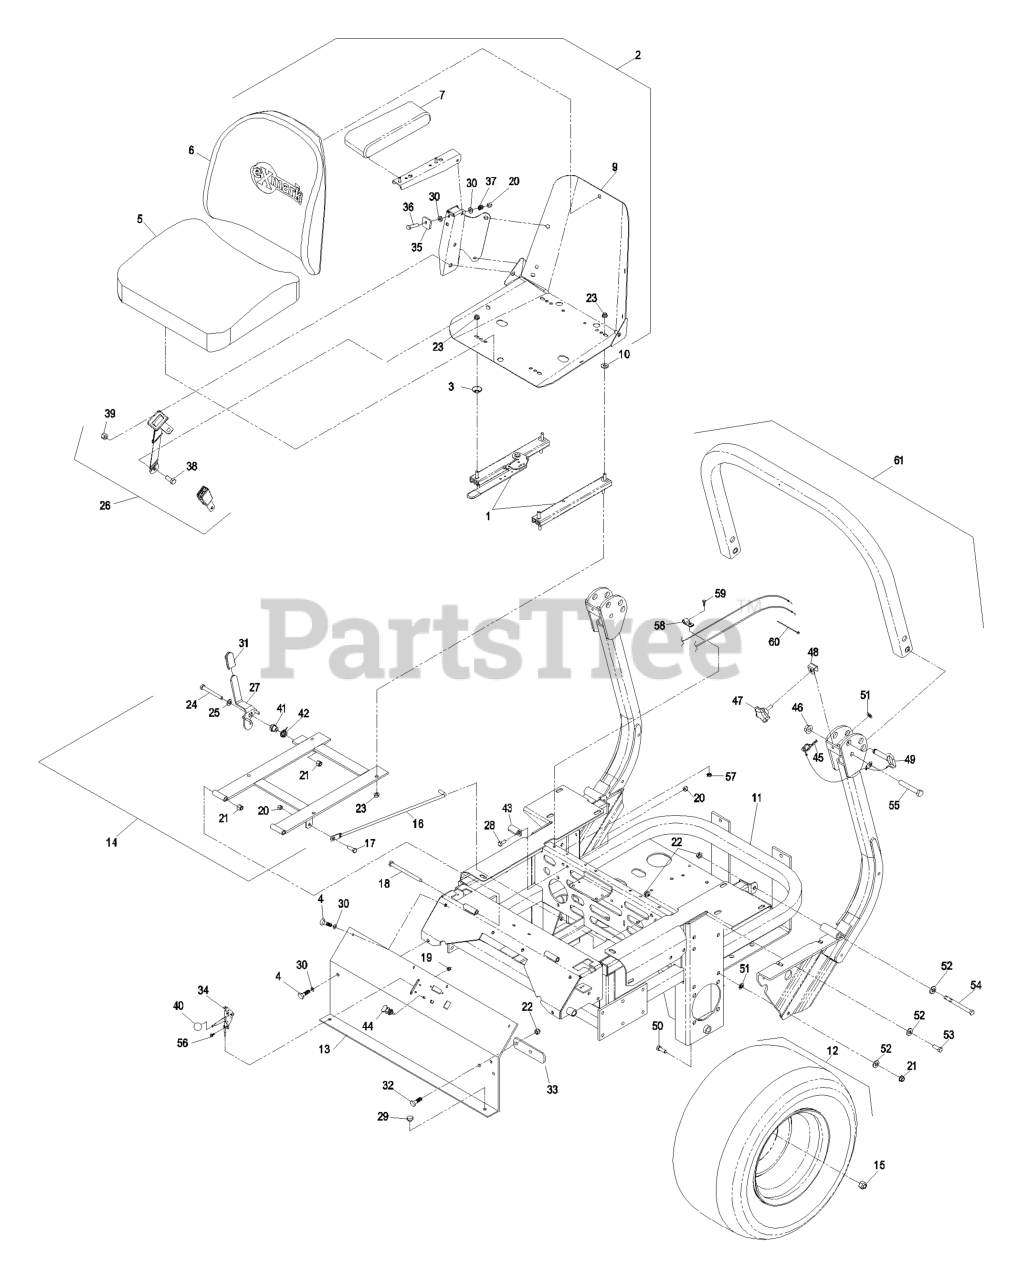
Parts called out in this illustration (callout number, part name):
1	TRACK-SEAT
2	KIT,SEAT W/ARMREST ADJ.
3	SPACER-TRACK
4	SCREW-HH
5	CUSHION,SEAT BOTTOM
6	CUSHION,SEAT BACK
7	CUSHION,ARMREST RH
9	FRAME-SEAT
10	WASHER-FLAT
14	ASM,SEAT FRAME
15	NUT-LUG
16	ROD-HOLDUP, SEAT
17	SCREW-HH
18	SCREW-HH
19	NUT-LOCK, NI
20	NUT-LOCK, NI
21	NUT-LOCK, NI
22	NUT-HHF, WHIZ
24	SCREW-HH
25	WASHER-FLAT
26	SEATBELT KIT
27	LATCH ASM
28	SCREW-HH
30	WASHER-PLAIN
31	GRIP-LEVER
32	SCREW-HH
33	STOP-BRAKE, PARK
34	THROTTLE CABLE ASM
35	TAB,ARMREST ADJUSTMENT
36	SCREW-HH
37	SPRING-TANK, FUEL
38	SCREW-HH
39	NUT-LOCK, NI
40	KNOB-BALL
41	BUSHING-LATCH, SEAT
42	SPRING-TORSION
43	CATCH-LATCH, SEAT
44	CONTROL-CHOKE
45	HAIRPIN
49	PIN-FOLD, ROPS
50	SCREW-HH
51	NUT-PUSH
52	WASHER-BELLEVILLE
53	SCREW-HH
54	SCREW-HH
55	SCREW-HH
56	BOLT-CARR
58	CLIP-LOOM
59	SCREW-HH
60	TIE-PLASTIC
61	KIT, LAZER Z 2 POST ROPS
